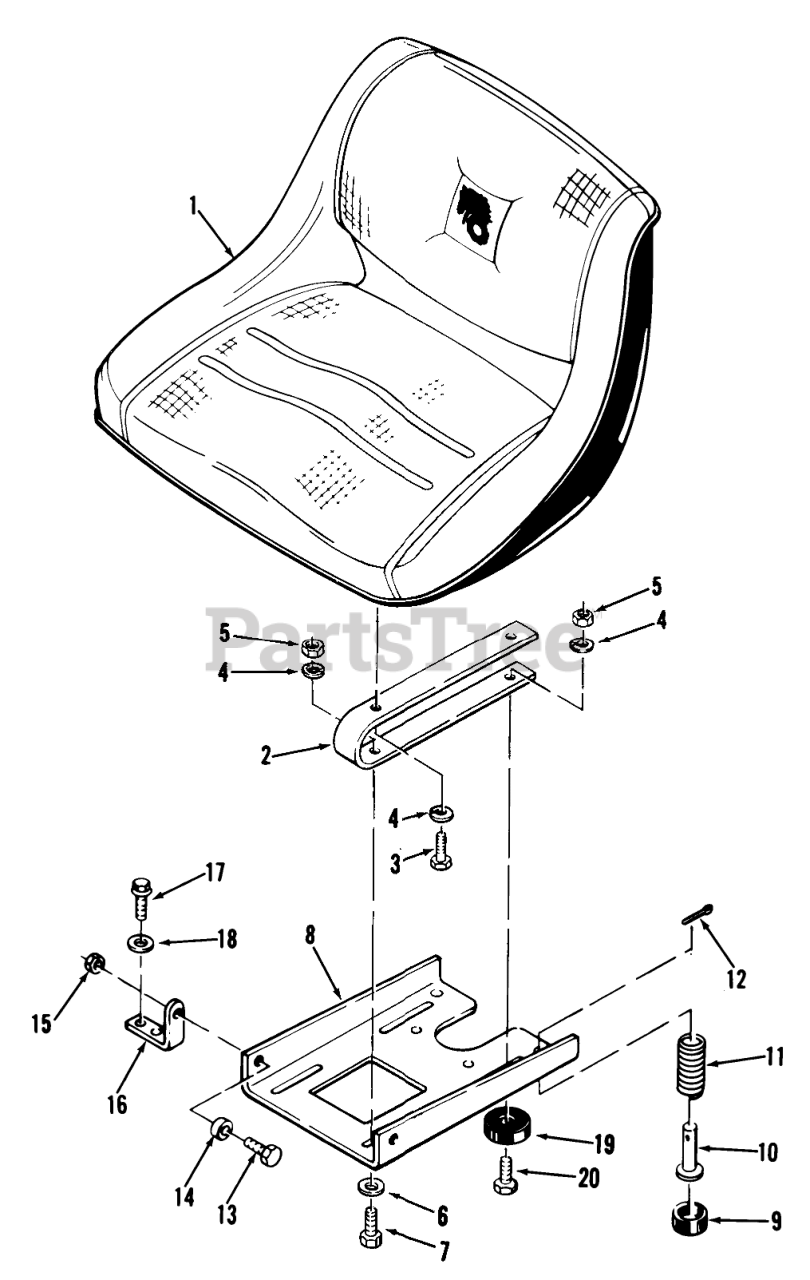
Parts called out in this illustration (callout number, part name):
1	Seat
2	Spring
3	Bolt
4	Lockwasher
5	Nut
6	WASHER 5/16 SAE
7	HHCS
8	Pivot Plate
11	SPRING
12	Cotter Pin
13	HHCS
14	BUSHING
15	Nut
16	BRACKET-PIVOT
17	SEAT BOLT FOR C195
18	WASHER 5/16 SAE
19	BUMPER
20	Bolt
